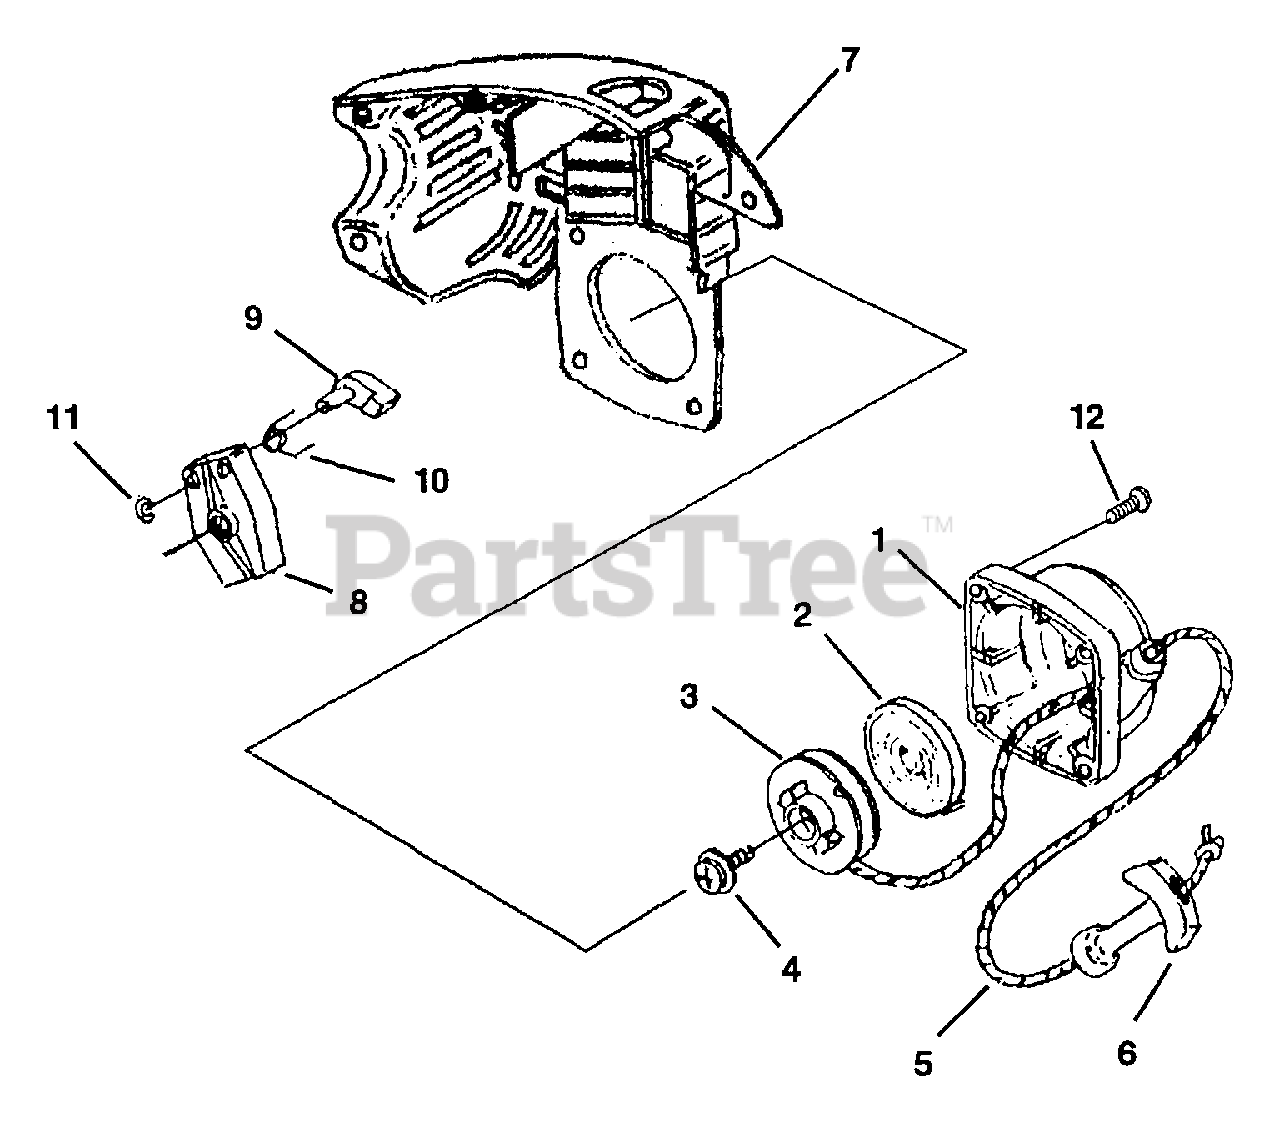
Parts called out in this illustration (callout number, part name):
1	HOUSING, STARTER
2	SPRING, RECOIL
3	PULLEY, STARTER
4	SCREW
5	ROPE, STARTER
6	GRIP, STARTER
7	SHROUD, COVER
8	CUP, STARTER
9	PAWL, STARTER
10	SPRING, STARTER PAWL
11	RING, RETAINER
12	SCREW
